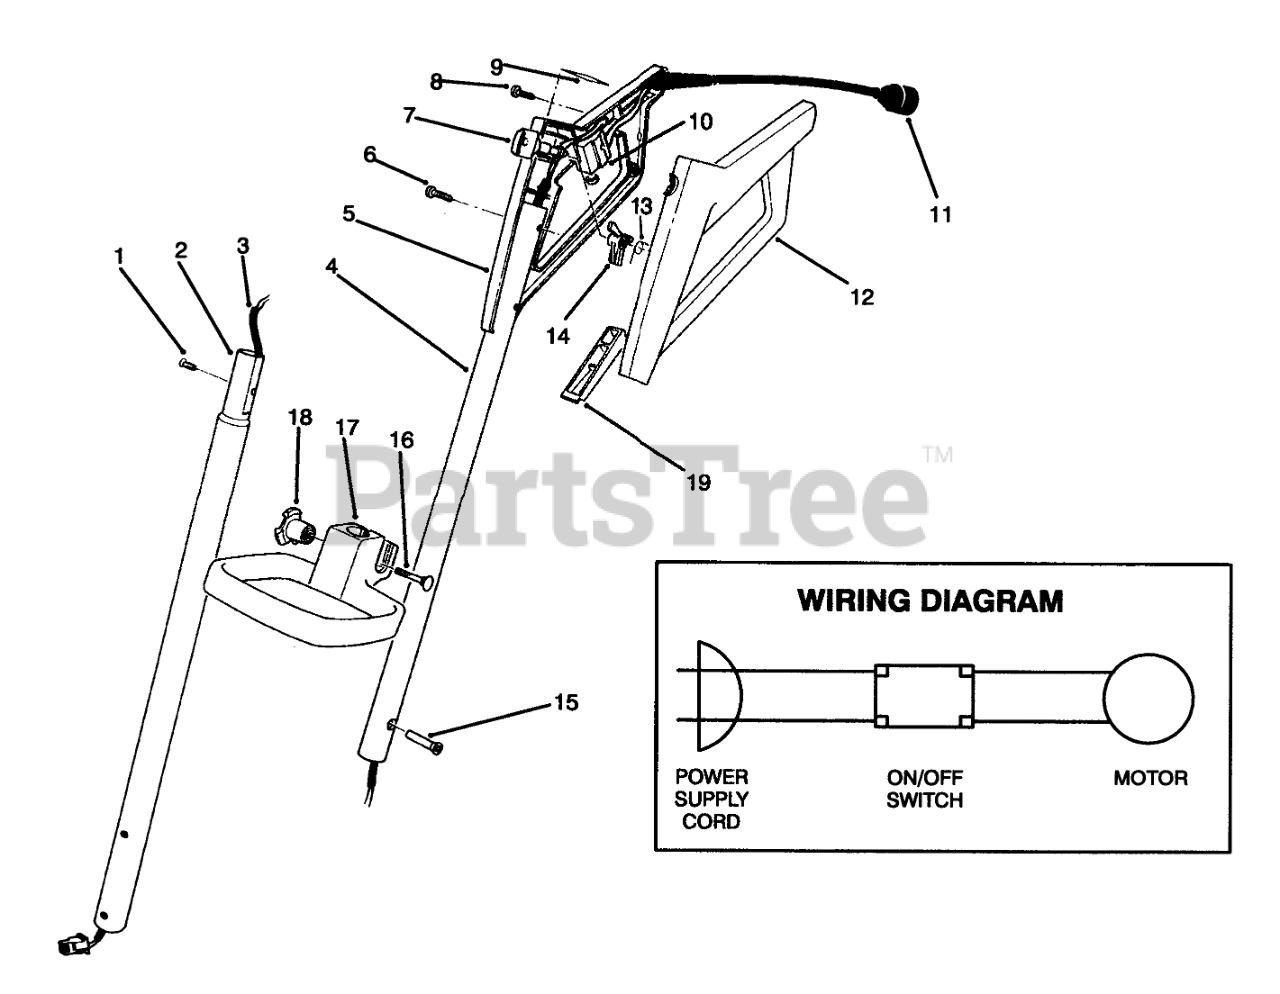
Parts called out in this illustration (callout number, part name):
1	SHOULDER SCREW
2	LOWER TUBE P. SHOVEL
3	WIRE HARNESS, P.S.
4	UPPER TUBE P. SHOVEL
5	PS-CONTROL GRIP, RH
6	Screw
8	SCREW-PPH
9	UL GRIP DECAL
10	SWITCH-STARTER
11	SUPPLY CORD, 1200
12	PS-CONTROL GRIP, LH
13	TORSION SPRING
14	LOCKOUT
15	COUNTER SUNK NUT
16	BOLT-CARR
17	PS-ADJUST HANDLE-BLK
18	HANDLE KNOB
19	SWITCH BAR,POWER SHOVEL
